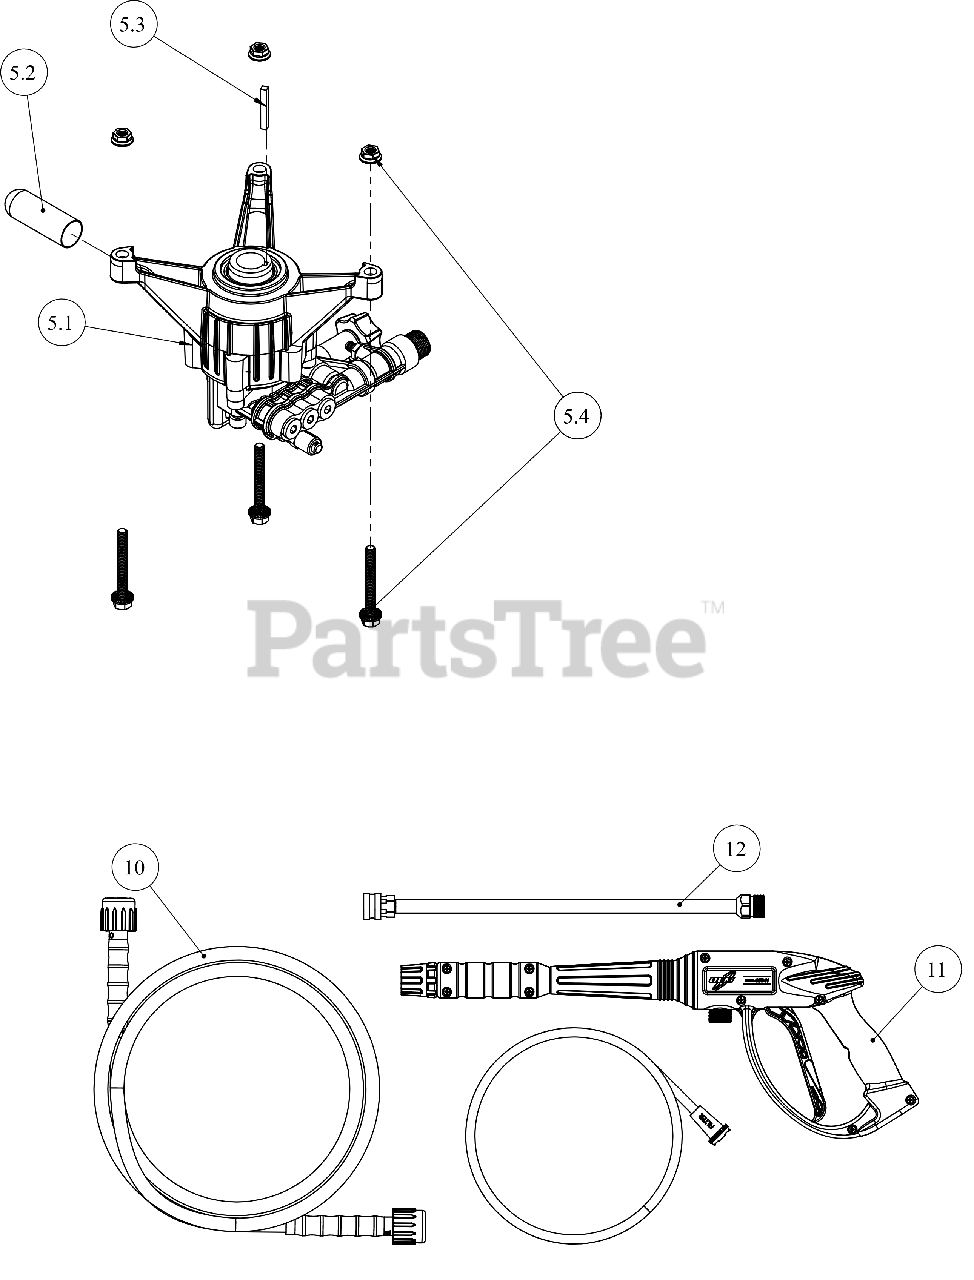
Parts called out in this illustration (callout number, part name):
5.1	PUMP (SVC 510020)
5.3	SHAFT KEY (3/16x3/16x1.5)
5.4	HARDWARE KIT-PUMP MTG
10	SPRAY GUN HOSE 30'
11	SPRAY GUN FRONT ENTRY
12	WAND-SPRAY GUN 16"
